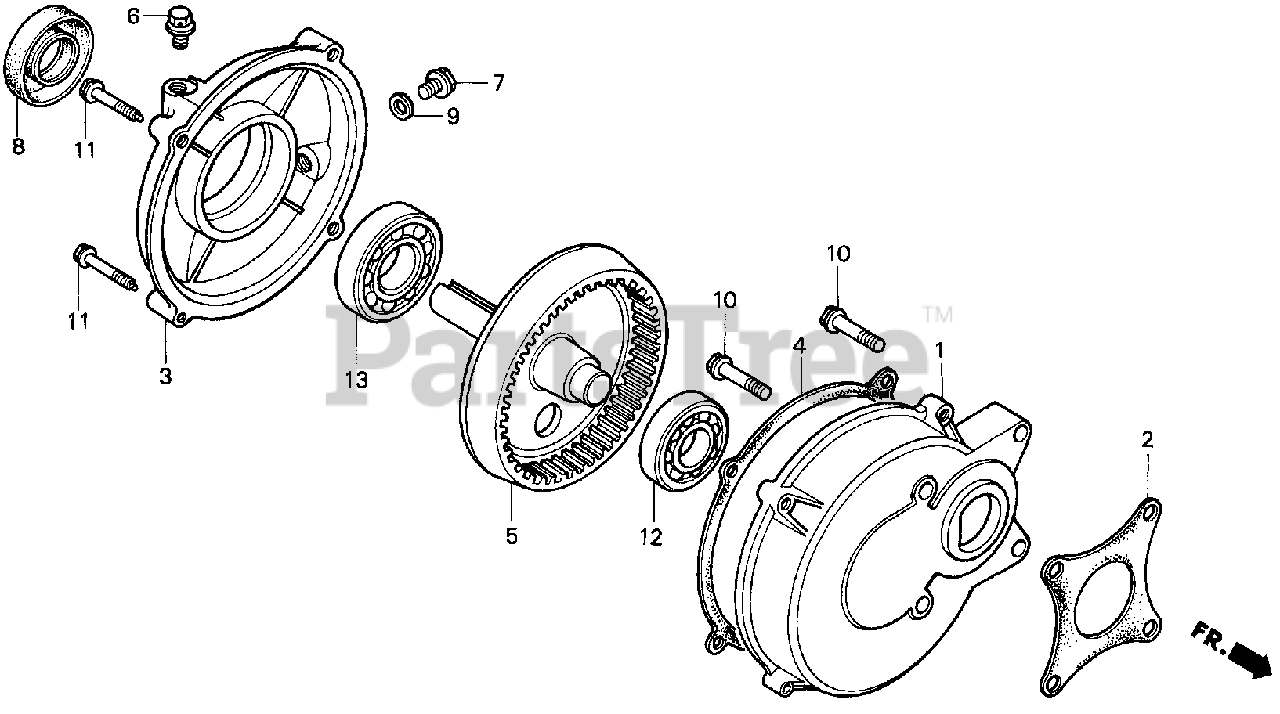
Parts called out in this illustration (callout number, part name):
1	CASE, REDUCTION
2	GASKET, REDUCTION CASE
3	COVER, REDUCTION
4	GASKET, REDUCTION COVER
5	SHAFT, P.T.O.
6	BOLT, BREATHING
7	BOLT, DRAIN PLUG
8	OIL SEAL (25X41X6)
9	WASHER, DRAIN PLUG (12MM)
10	BOLT, FLANGE (8X32)
11	BOLT, FLANGE (8X35)
12	BEARING, RADIAL BALL (6204)
13	BEARING, RADIAL BALL (6305)
